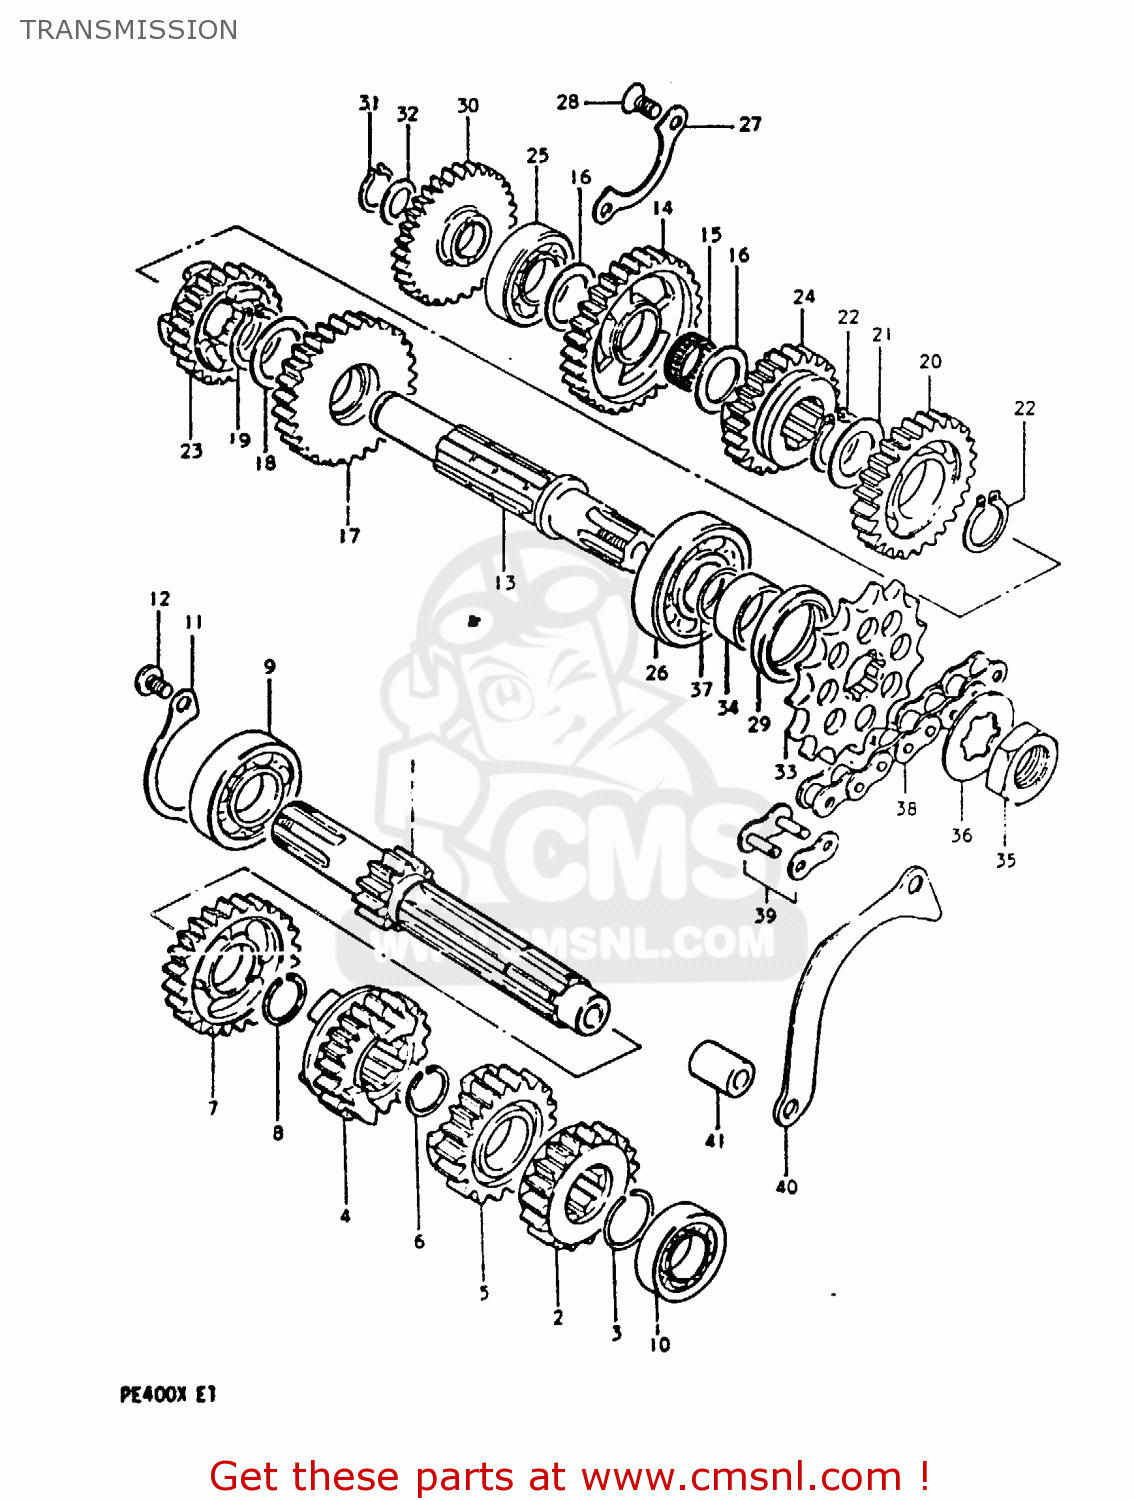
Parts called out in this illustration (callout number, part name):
1	SHAFT,COUNTER
2	GEAR,SECOND DRIVE
3	CIRCLIP
4	GEAR,THIRD DRIVE
5	GEAR,FOURTH DRIVE
6	CIRCLIP
7	GEAR,FIFTH DRIVE
8	CIRCLIP
9	BEARING
10	BEARING
11	PLATE,COUNTERSHAFT BEARING
12	SCREW 6X12
13	SHAFT,DRIVE
14	GEAR,FIRST DRIVEN
15	BEARING(17X21X9.8)
16	WASHER
17	GEAR,SECOND DRIVEN
18	SHIM
19	CIRCLIP
20	GEAR,THIRD DRIVEN
21	WASHER
22	CIRCLIP
23	GEAR,FOURTH DRIVEN
24	GEAR,FIFTH DRIVEN
25	BEARING
26	BEARING
27	PLATE,DRIVESHAFT BEARING
28	SCREW
29	SEAL,OIL(32X42X6)
30	GEAR,KICK STARTER IDLE
31	CIRCLIP
32	WASHER
33	SPROCKET,ENGINE
34	SPACER(22X32X11.5)
35	NUT
36	WASHER,LOCK
37	O RING(D:1.7,ID:22)
38	CHAIN ASSEMBLY,DRIVE
39	JOINT ASSEMBLY,CHAIN
40	PLATE,FR CHAIN GUIDE
41	SPACER(8.6X16X24)
